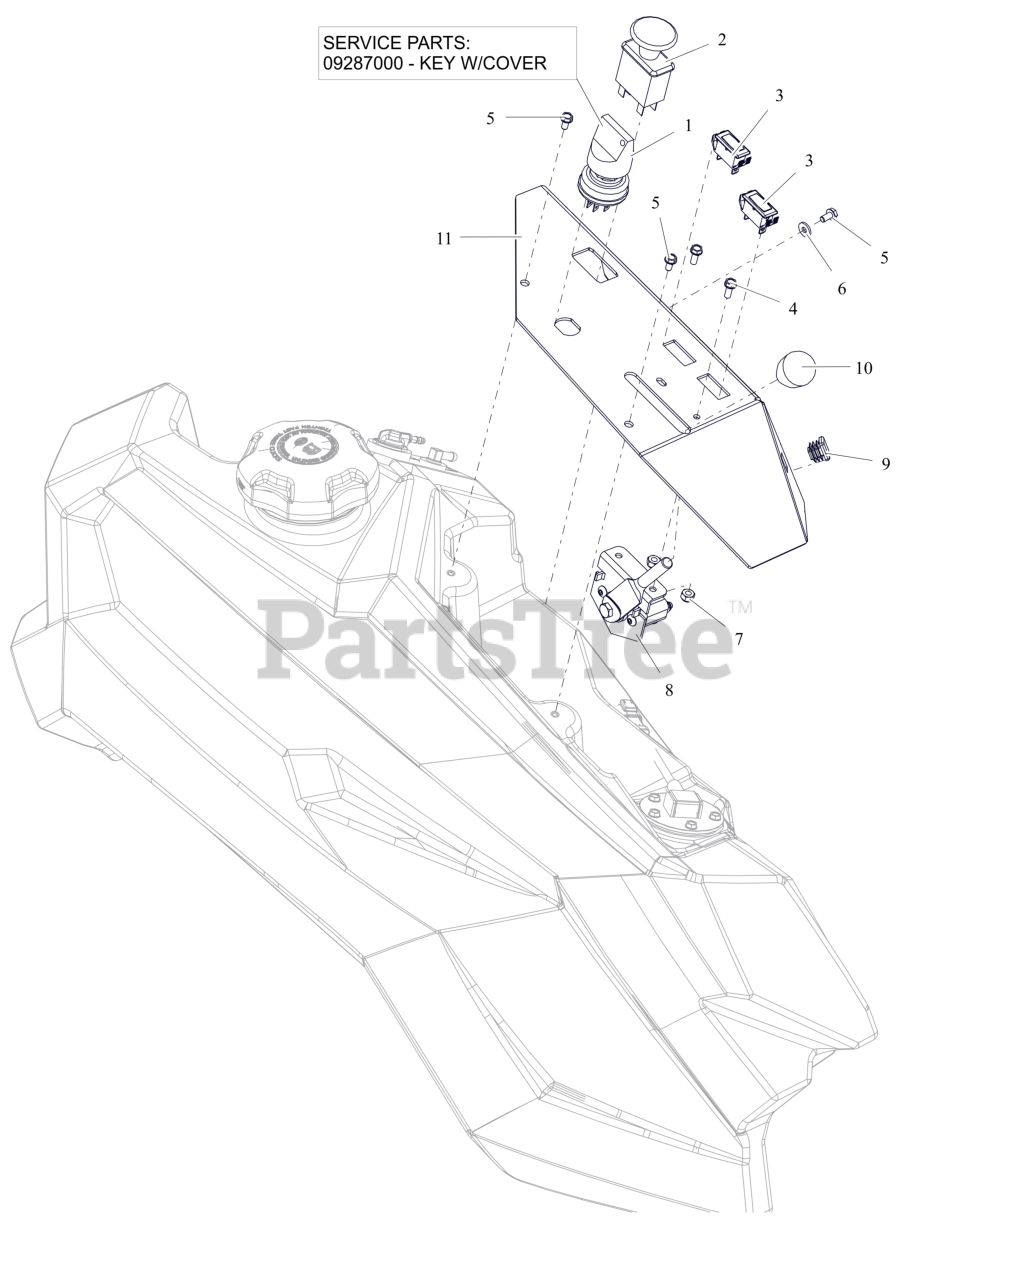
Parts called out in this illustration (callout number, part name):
1	SWITCH, IGNITION
1	KEY, W/ SHIELD
2	SWITCH, CLUTCH
3	LIGHT, INDICATOR (RED)
4	BLT, HWH #10-24X.50 ZCC
5	SCR-MCH 10-24X.38 HWHSTAINLESS
6	WSHR-FL-STL .196X.50X.06 ZC120
7	NUT-LK-NYL #10-24 G2 ZCC
8	CONTROL, ELECTRONIC THROTTLE
9	PLUG, 5/8" SQ BLACK (14-20GA)
10	KNOB-CONTROL-BLACK .38-16X.50
11	PANEL, RH CONTROL (RED)
